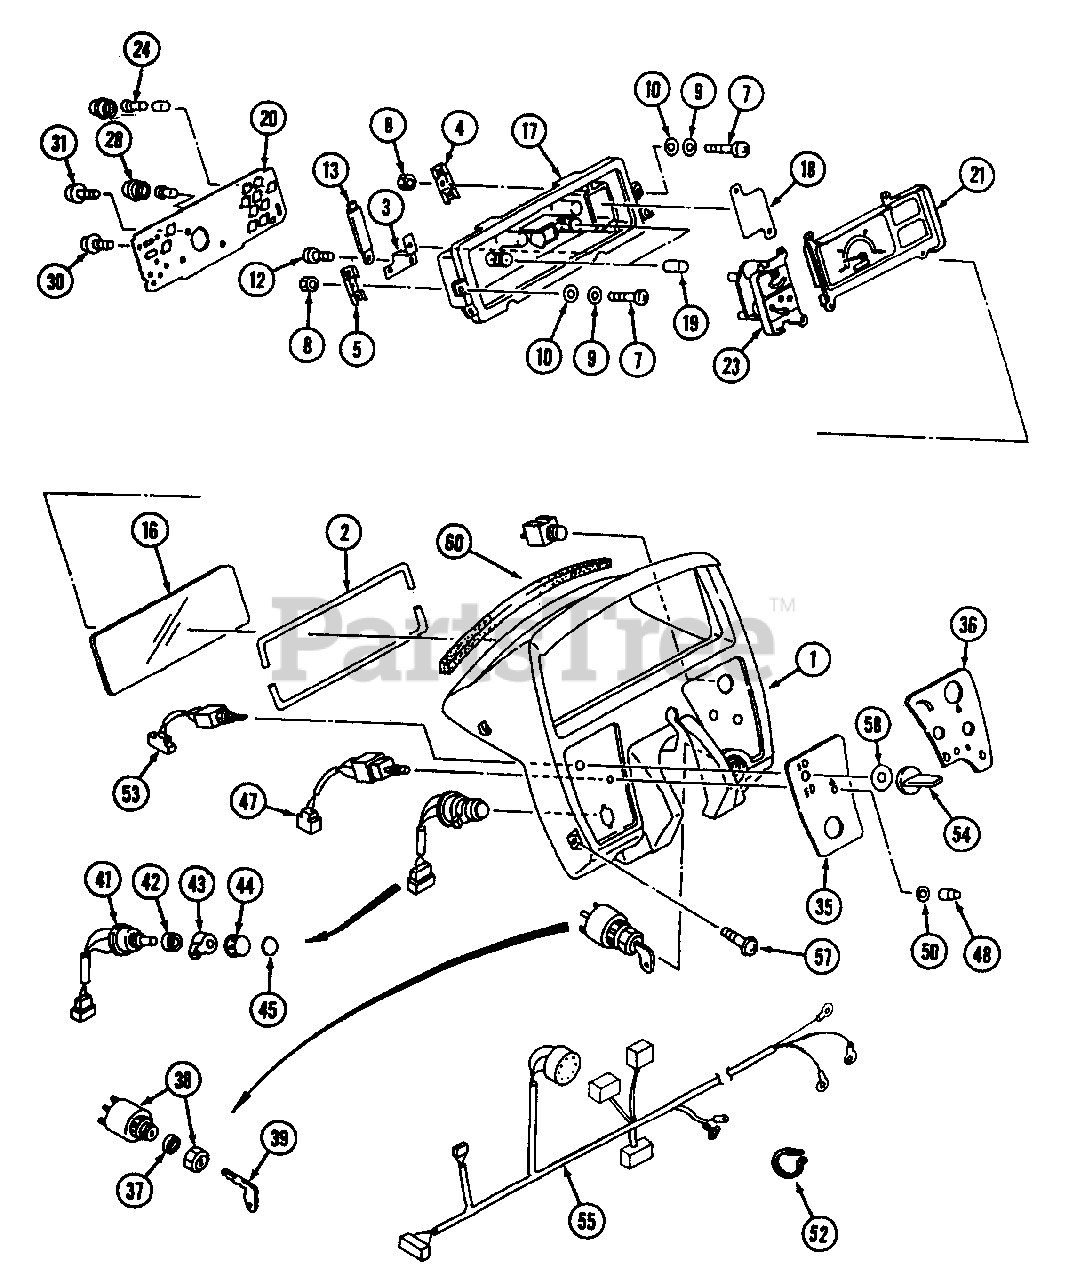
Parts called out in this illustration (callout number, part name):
16	Glass Ass'y.
18	Plate, Monitor
19	Lens, Indicator
20	Board, Print
23	Meter, Fuel & Temp.
35	Label, Panel L.H.
36	Label, Panel R.H.
37	Packing, Starter
38	Switch, Starter
39	Key, Starter
41	Switch, Body Ass'y.
42	Ring, Nut
43	Flasher, Lever
44	Lighting, Knob
53	Switch,Light H/L
58	Packing, Rubber
